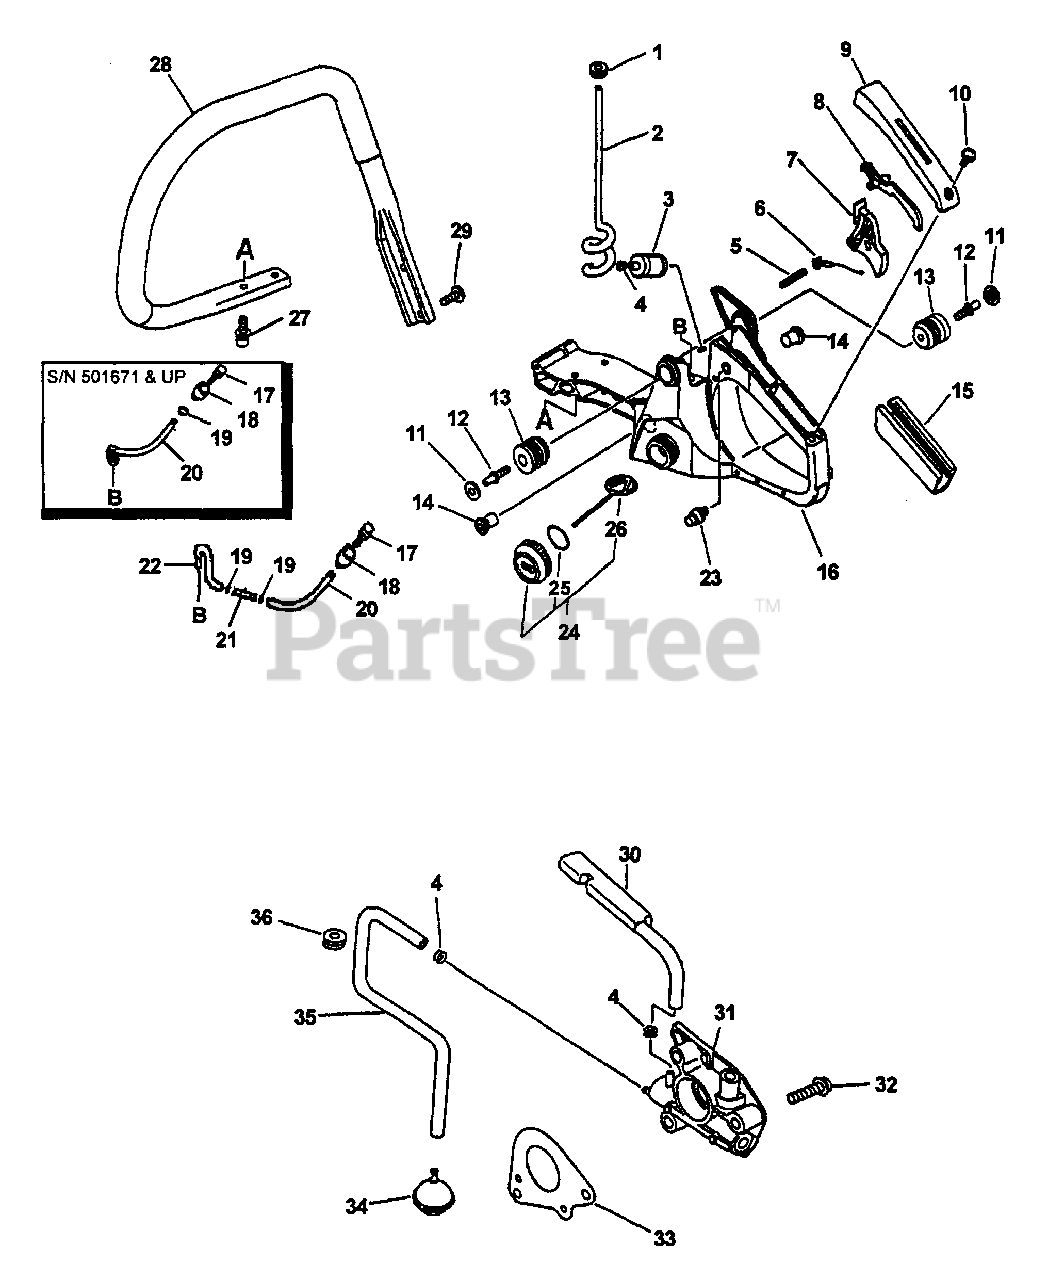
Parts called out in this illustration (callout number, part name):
2	PIPE, FUEL - SPIRAL
3	FILTER, FUEL
4	CLIP - 6.5
5	PIN - SPRING -- 4X30
6	SPRING, TRIGGER
7	TRIGGER, THROTTLE
8	LEVER, TRIGGER LOCKOUT
9	COVER, HANDLE
10	SCREW - 4X14
11	CAP, CUSHION
15	GRIP, HANDLE
16	HANDLE KIT - REAR
17	VENT, FUEL TANK
18	COVER, VENT
19	CLIP - 5.5
19	CLIP - 6.5
20	PIPE - 3X5X100 -- BLACK
20	PIPE - VENT
21	CONNECTOR, PIPE
22	PIPE
23	LATCH, THROTTLE
24	CAP ASSY - ORANGE
25	O-RING - 22
26	CONNECTOR, CAP
27	SCREW - 5X16 -- TAPPING
28	HANDLE - FRONT
29	SCREW - 5X20 -- TAPPING
30	PIPE - OIL
31	AUTO-OILER ASSY
32	SCREW - 4X16
33	SEAL, DUST
34	FILTER, OIL
35	PIPE - OIL
